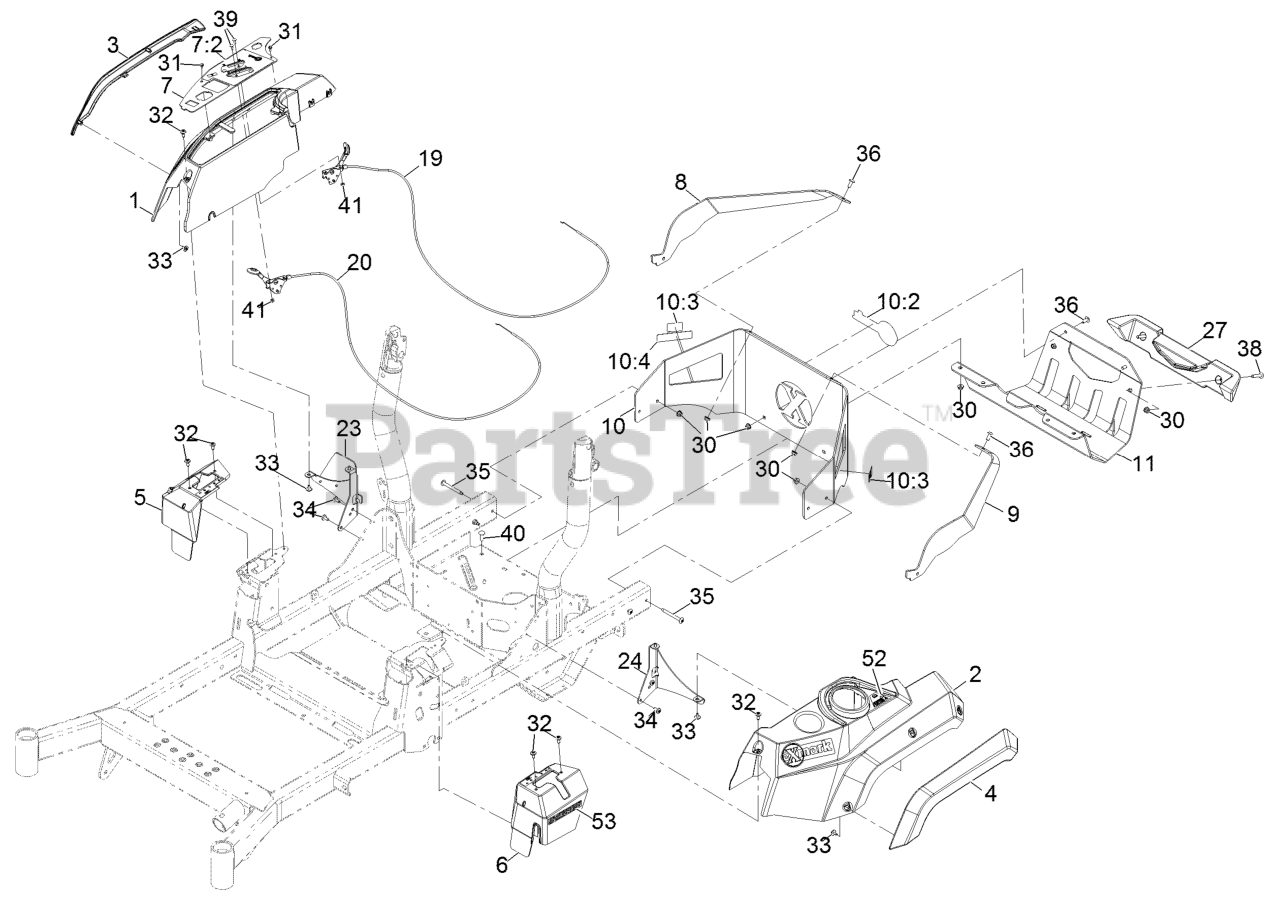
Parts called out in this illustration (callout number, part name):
1	CONSOLE-EXMARK, RH
2	CONSOLE, LH
3	FENDER-RH
4	FENDER-LH
5	COVER-CONTROL, MOTION (RH
6	COVER-CONTROL, MOTION (LH
7	ASM-CTRL PANEL W/DCL
7:2	DECAL-CONTROL PANEL
8	SUPPORT-UPPER, RH
9	SUPPORT-UPPER, LH
10	REAR GUARD ASM
10:2	DECAL-EXMARK LOGO
10:3	DECAL-WARNING
10:4	DECAL-ARRESTER, SPARK
11	GUARD-MUFFLER
19	CABLE-CONTROL, CHOKE
20	CABLE-CONTROL, THROTTLE
23	SUPPORT-CONSOLE, RH
24	BRACKET-CONSOLE, LH
30	NUT-HF, NI
31	SCREW-HWH
32	SCREW-SHOULDER
33	SCREW-TORX
34	SCREW-TORX
35	SCREW-TORX
36	SCREW-TORX
38	SCREW-TORX
39	BOLT-CARR
40	SCREW-CARR
41	NUT-LOCK, NI
52	DECAL-FILL, FUEL
53	DECAL-S-SERIES
